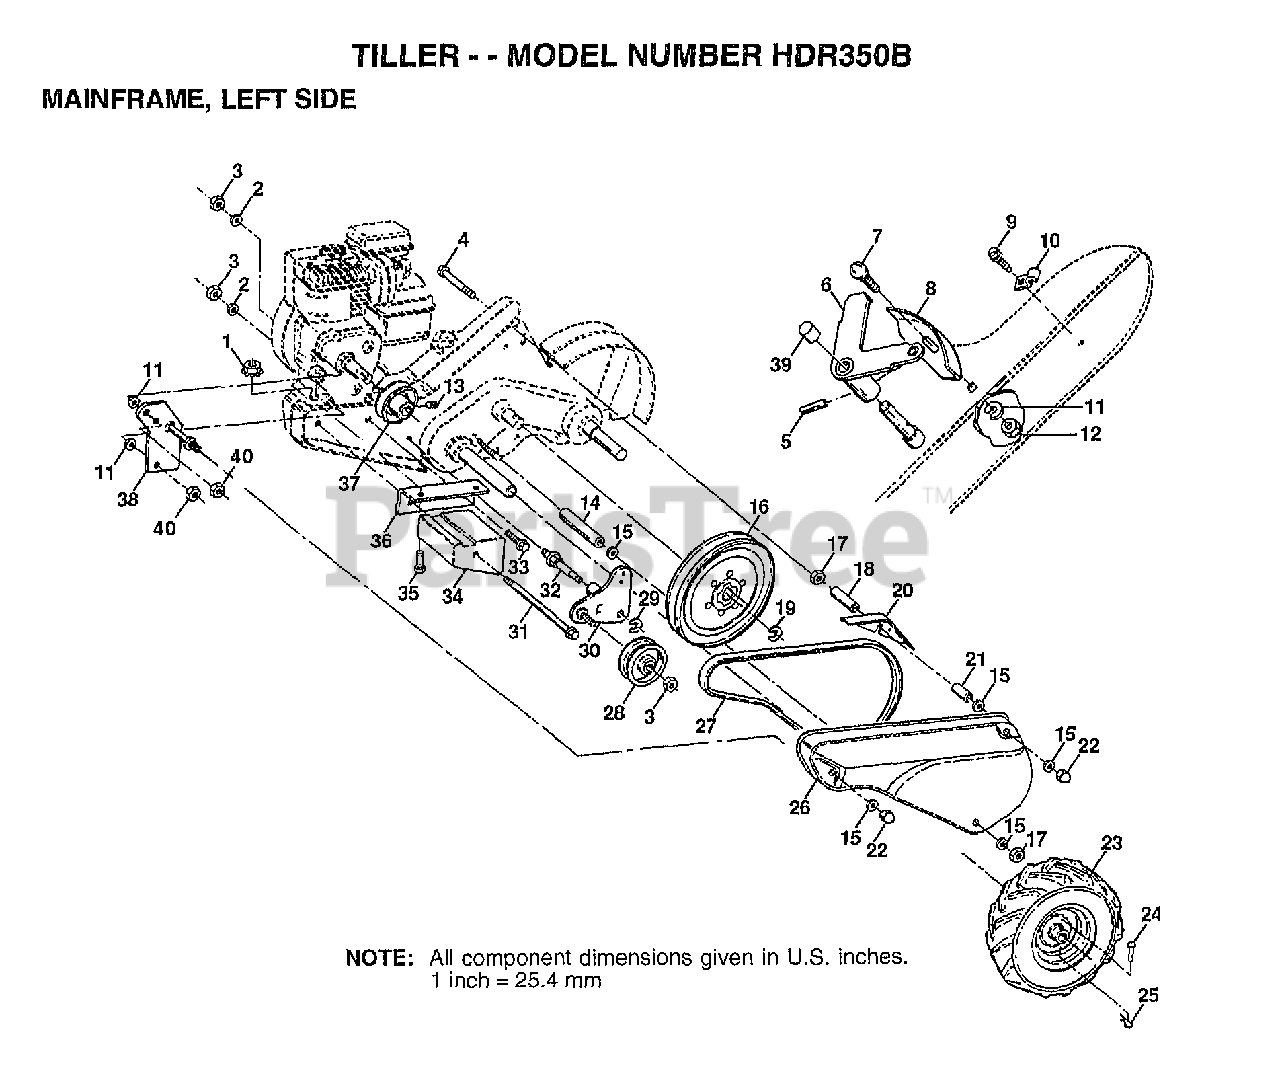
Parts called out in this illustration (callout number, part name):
2	LOCKWASHER
3	NUT.HEX.3/8-16UNC
4	BOLT TI
6	LEVER ASM CRT
7	BOLT
8	PANEL TI
10	CONDIUT CLIP T
11	LOCKWASHER
13	SET SCREW
14	SPACER
15	WASHER
16	SHEAVE.TRANS.
17	NUT.HEX.5/16-18
20	GUARD CRT
21	SPACER.SPLIT
22	NUT TI
23	TIRE.CHV.13X5.0-6
23	RIM
24	RIVET.DRILL.1.75
25	RETAINER M
26	GUARD.BELT.PNT.
27	BELT-V
28	PULLEY-IDLER TI
29	KLIP RING
31	BOLT CRT
32	SHIFT ARM CRT
33	BOLT
34	COUNTERWEIGHT CRT
35	BOLT.HEX.5/16-1.5
36	BRACKET LH CRT
37	ENGINE SHEAVE
38	BELT GUARD BRKT
39	CAP PLUNGER BLACK
40	NUT
